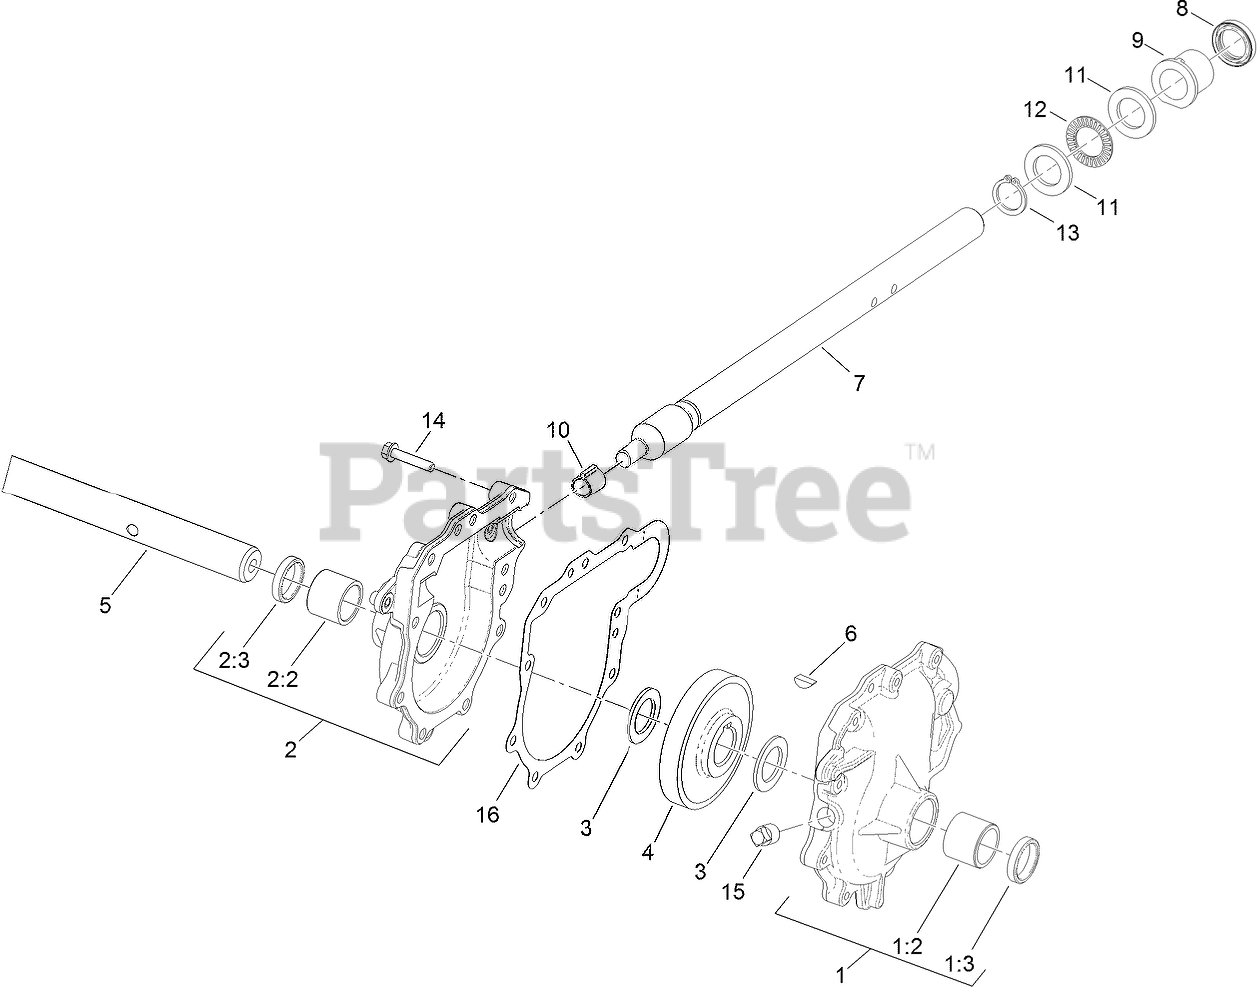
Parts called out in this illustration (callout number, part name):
1	LH AUGER GEARCASE ASM
1:2	BUSHING-SLEEVE
1:3	SEAL-OIL
2	RH AUGER GEARCASE ASM
2:2	BUSHING-SLEEVE
2:3	SEAL-OIL
3	WASHER-THRUST
4	GEAR-HELICAL
5	SHAFT-AUGER
6	KEY-WOODRUFF
7	SHAFT-IMPELLER
8	SEAL-OIL
9	BUSHING-INPUT
10	BUSHING-WORM
11	WASHER-THRUST
12	BEARING-THRUST
13	RING-RETAINING, Ext
14	SCREW-HWHTF
15	PLUG-PIPE, SQH
16	GASKET-GEARCASE, AUGER
